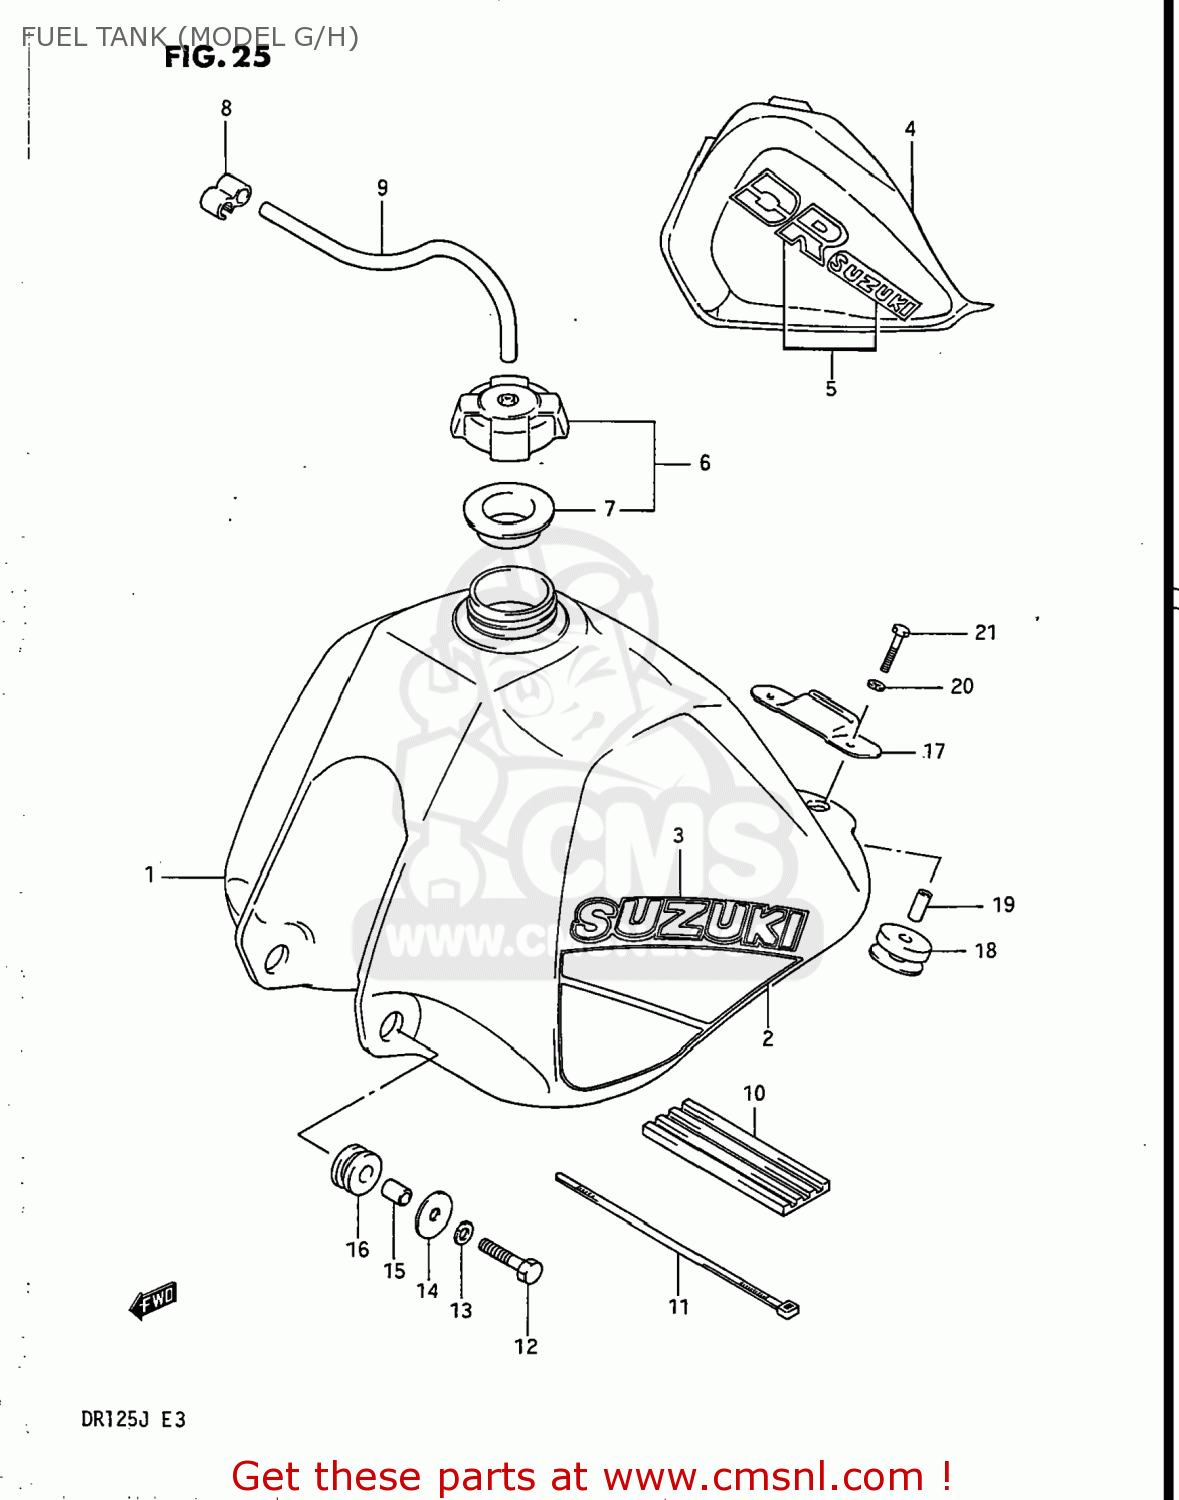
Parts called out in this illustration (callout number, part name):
1	TANK ASSEMBLY,FUEL
2	TAPE SET,FUEL TANK
3	EMBLEM
4	TANK ASSEMBLY,FUEL
5	TAPE SET,FUEL TANK
6	CAP SET,FUEL TANK
7	GASKET,FUEL TANK CAP (NAS)
8	CLAMP,FUEL TANK BREATHER HOSE
9	HOSE
10	CUSHION,FUEL TANK UPR FR
11	CLAMP
12	BOLT
13	LOCK WASHER
14	WASHER (8.5X29X1.6)
15	SPACER (8.8X12X13.5)
16	CUSHION
17	PLATE,SEAT FR HOOK
18	CUSHION
19	SPACER
20	WASHER,LOCK
21	BOLT
